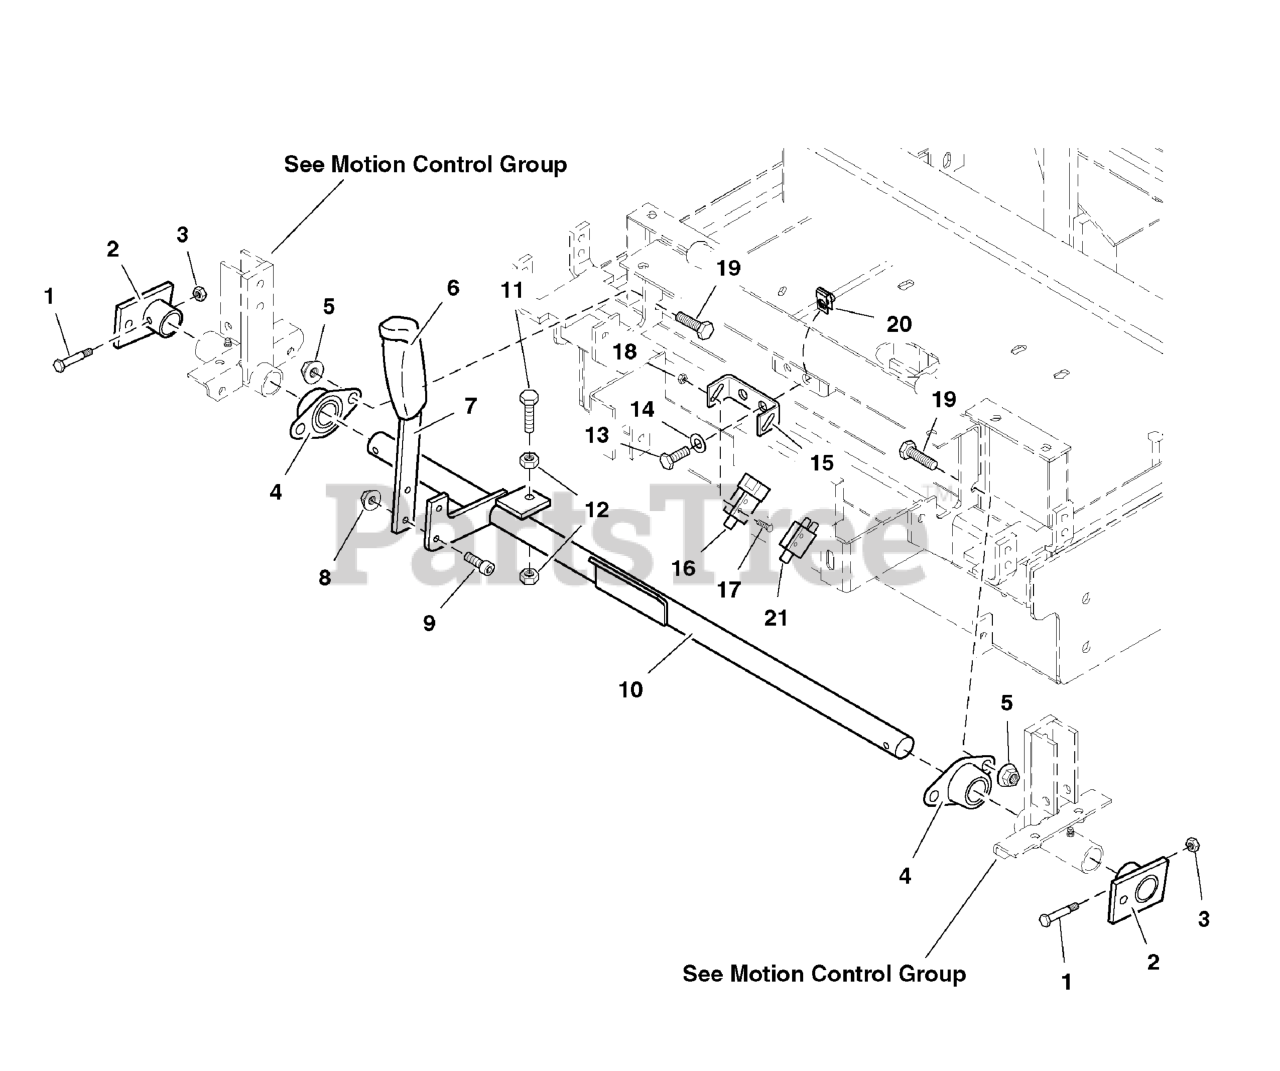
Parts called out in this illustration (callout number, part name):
1	BOLT, 1/4-20 X 1-1/2
2	BRAKE LINKAGE PIVOT
3	NUT, 1/4-20 Hex Side Lock
4	BEARING, Flange
5	NUT, 3/8-16 Hex Serrated Flange
6	GRIP
7	BRAKE HANDLE
8	NUT, 5/16-18 HEX SERRATED FLANGE (SMALL)
9	CAPSCREW, Socket Button Head, 5/16-18 x 3/4
10	BRAKE SHAFT
11	BOLT, 3/8-16 X 2, GD5, CZ
12	NUT, 3/8-16 HEX JAM
13	BOLT, 5/16-18 X 3/4 GD5
14	WASHER, 5/16" SAE
15	BRAKE SWITCH MOUNT
16	SWITCH, PLUNGER, N.O./N.C.
17	SCREW, #10-24 X 1 RS, CZ
18	NUT, #10-24 Hex
19	BOLT, 3/8-16 X 3/4" GD5 CZ
20	BODY CLIP, 5/16-18-7GA MATERIAL
21	SWITCH, Plunger, NO
21	SWITCH, PLUNGER, N.O./N.C.
